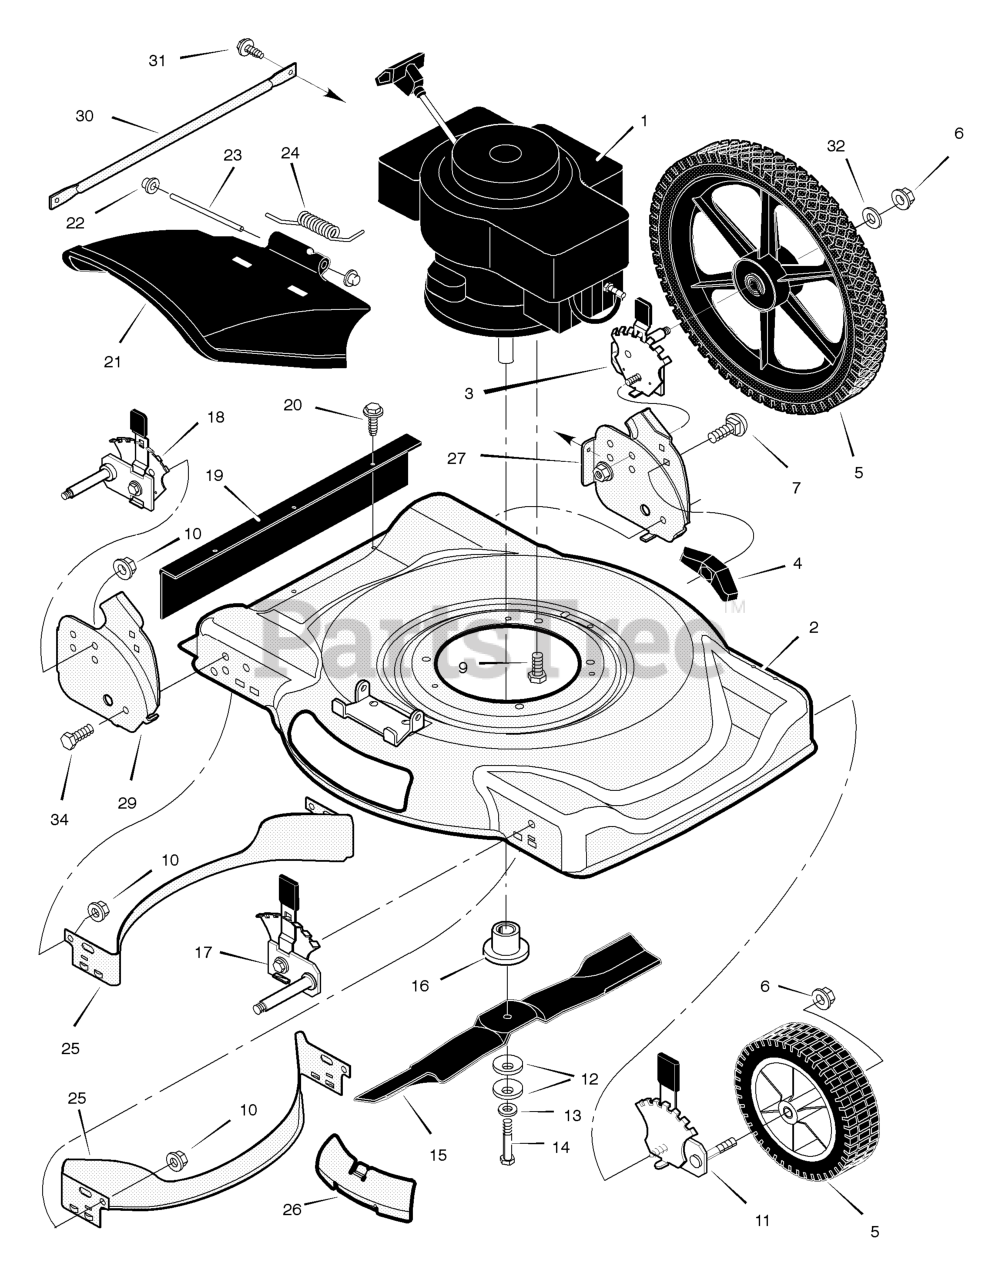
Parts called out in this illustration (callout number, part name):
1	Engine *
2	Housing
3	Height Adjuster, Left Rear
5	Wheel and Tire - Front
5	Wheel and Tire - Rear
6	Locknut, Flange
7	Bolt, Carriage
9	Bolt, Engine
10	Nut
11	Height Adjuster, Left Front
12	Washer, Belleville
14	Bolt, Hex
16	Adapter, Blade
17	Height Adjuster, Right Front
18	Height Adjuster, Right Rear
19	Guard, Rear
21	Deflector, Chute
22	Push-On Cap
23	Pin, Pivot
26	Plate, Mulcher
27	Bracket, Left Handle
29	Bracket, Right Handle
34	Bolt
